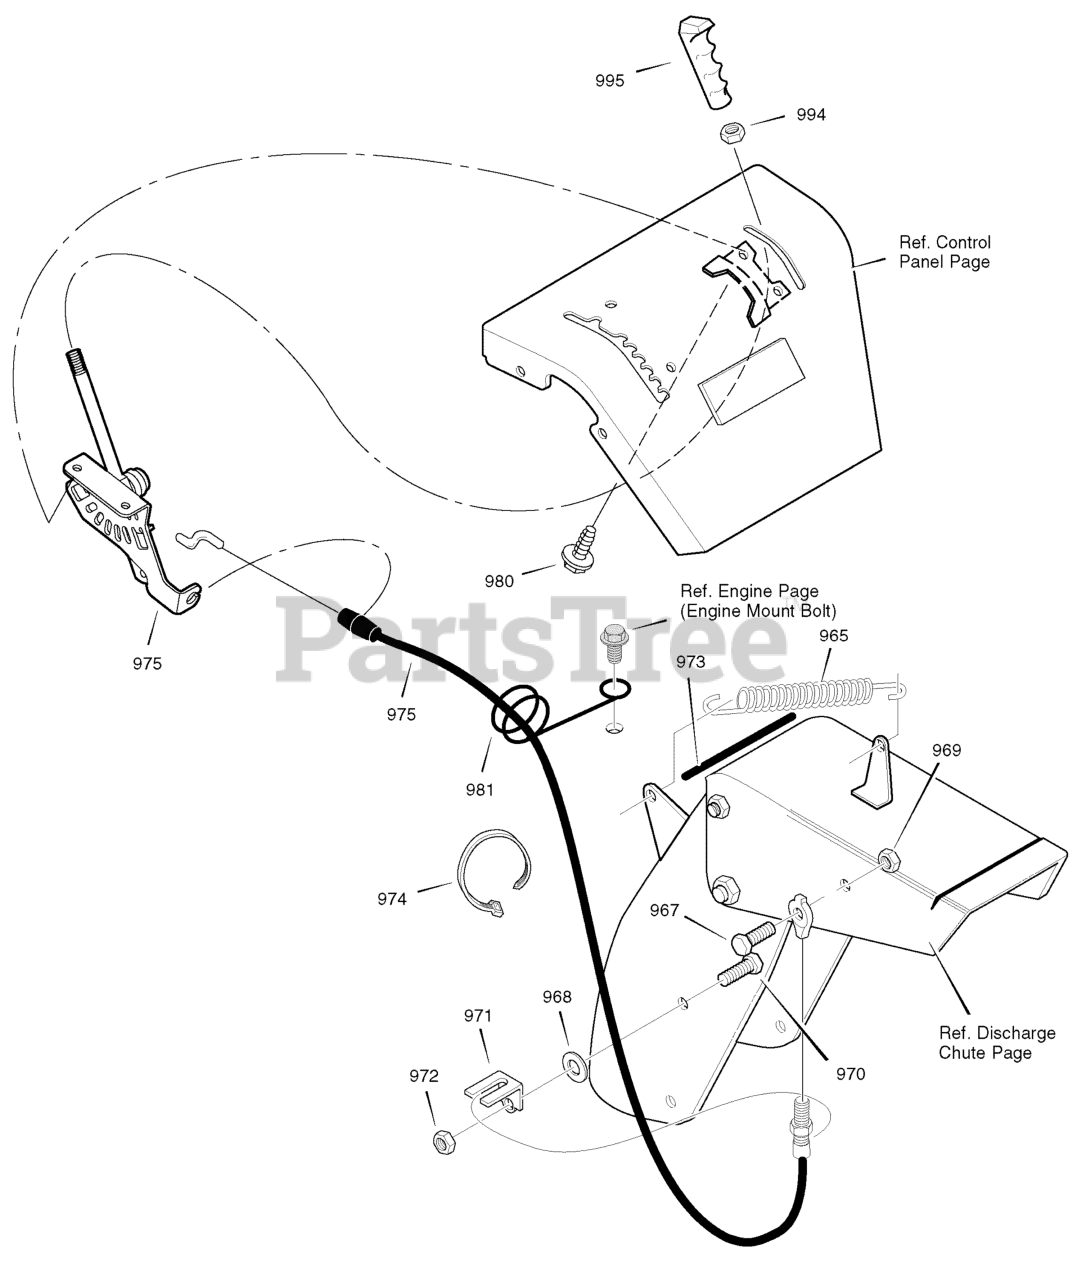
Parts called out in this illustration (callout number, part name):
965	TENSION SPRING
967	BOLT
968	FLATWASHER
969	NUT
971	BRACKET, CABLE CHUTE
972	NUT
973	TRIM STRIP
974	TIE, CABLE
975	ASSY, CHUTE DEF. CONTROL
981	WIRE FORM, REMOTE CHUTE CABLE
